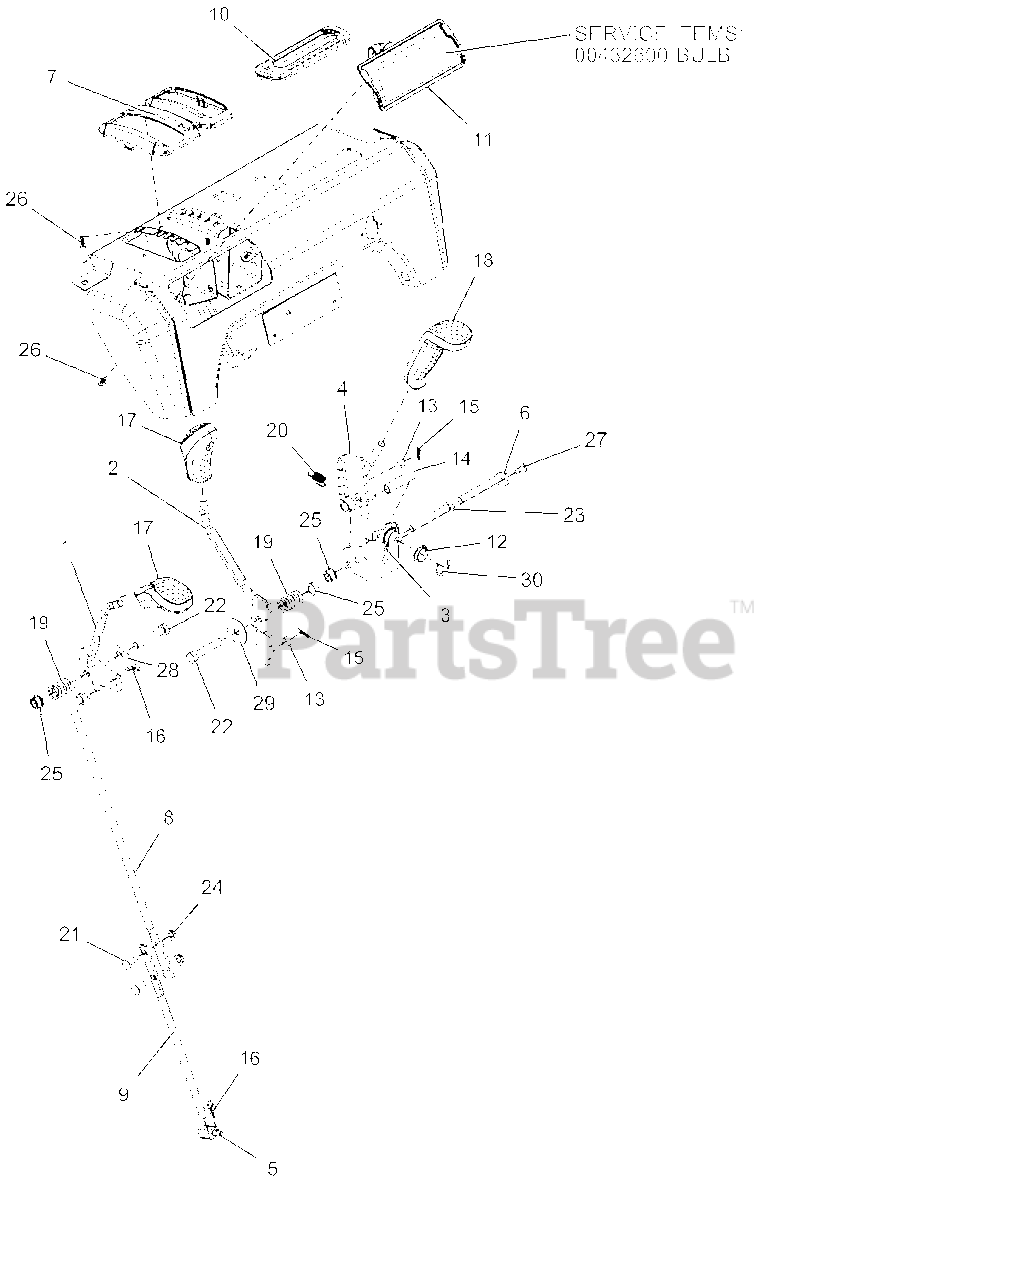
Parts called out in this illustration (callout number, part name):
1	WELDMENT,LG DASH SPEED CONTROL
2	WELDMENT,LG DASH DEFL CONTROL
3	WELDMENT-CONTROL BRACKET-CHUTE
4	WELDMENT,LG DASH QT CONTROL
5	PIVOT,SHIFT ROD .375-16(TRUNN)
6	ROD, PIVOT - INTERLOCK
7	BEZEL, SHIFT - FRICTION SNOW
8	ROD, SHIFT - UPPER
9	ROD, SHIFT - LOWER
10	GROMMET, BOOT, QUICK TURN
11	BULB, LIGHT-HALOGEN 20W
11	HEADLIGHT ASY, HALO 20W 2SHOT
12	BUSHING, POLYLINER-.75 SNAPIN
13	BSHG-SLV .265X.500X.219
14	SPCR, WHEEL .385X.500X2.00
15	PIN-HAIR INT .06X.18X.77
16	PIN-HAIR INT .08X.18X1.18 YWZC
17	KNOB, CONTROL, DASH
18	HANDLE, QUICK TURN, ASM
19	SG-COMP .125X.781X1.250
20	SPRING-EXT .047X.438X1.45
21	@BLT-RDHDSQNK .25-20X.75 G5YZ
22	@BLT-HEX .38-16X2.00 GR5 YWZC
23	@BLT-HEX .38-16X2.75 GR5 YWZC
24	@NUT-LK-CTR-FLG .25-20 YWZC
25	@NUT-LK-TOP-FLG .38-16 YWZC
26	SCR-TAP #10X.50 BOSS INDHXHD
27	SCR-TAP .25-20X.50 HWH TR YWZ
28	WSHR-FL-STL .406X1.00X.188 YWZ
29	WSHR-FL-STL .380X1.50X.062 YWZ
30	E-RING .750X.050
